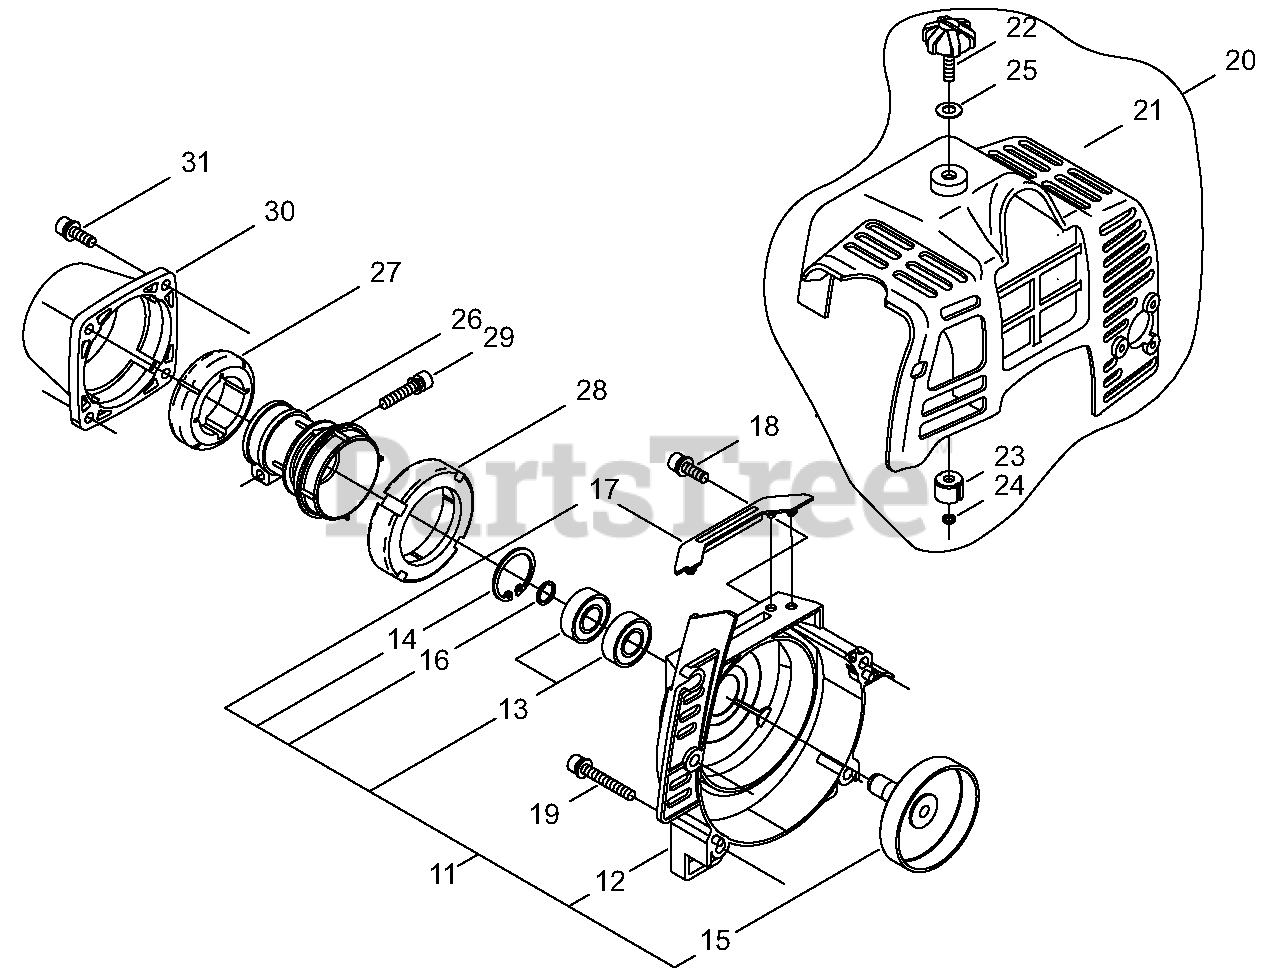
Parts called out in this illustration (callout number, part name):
11	COVER ASSY, FAN
12	COVER, FAN
13	BEARING, BALL 6000ZZ
14	RING, SNAP Ø26
15	DRUM, CLUTCH
16	RING, SNAP WR10
17	CUSHION
18	BOLT M5×16
19	BOLT M5×45
20	COVER ASSY, ENGINE
21	COVER, ENGINE
22	THUMBSCREW
23	INSULATOR 5 MM
25	WASHER, CONE M6
26	CUSHION, AV
27	CUSHION, FRONT
28	HOLDER, REAR CUSHION
29	BOLT M5×25
30	COVER, AV CUSHION (RED)
31	BOLT M5×16
